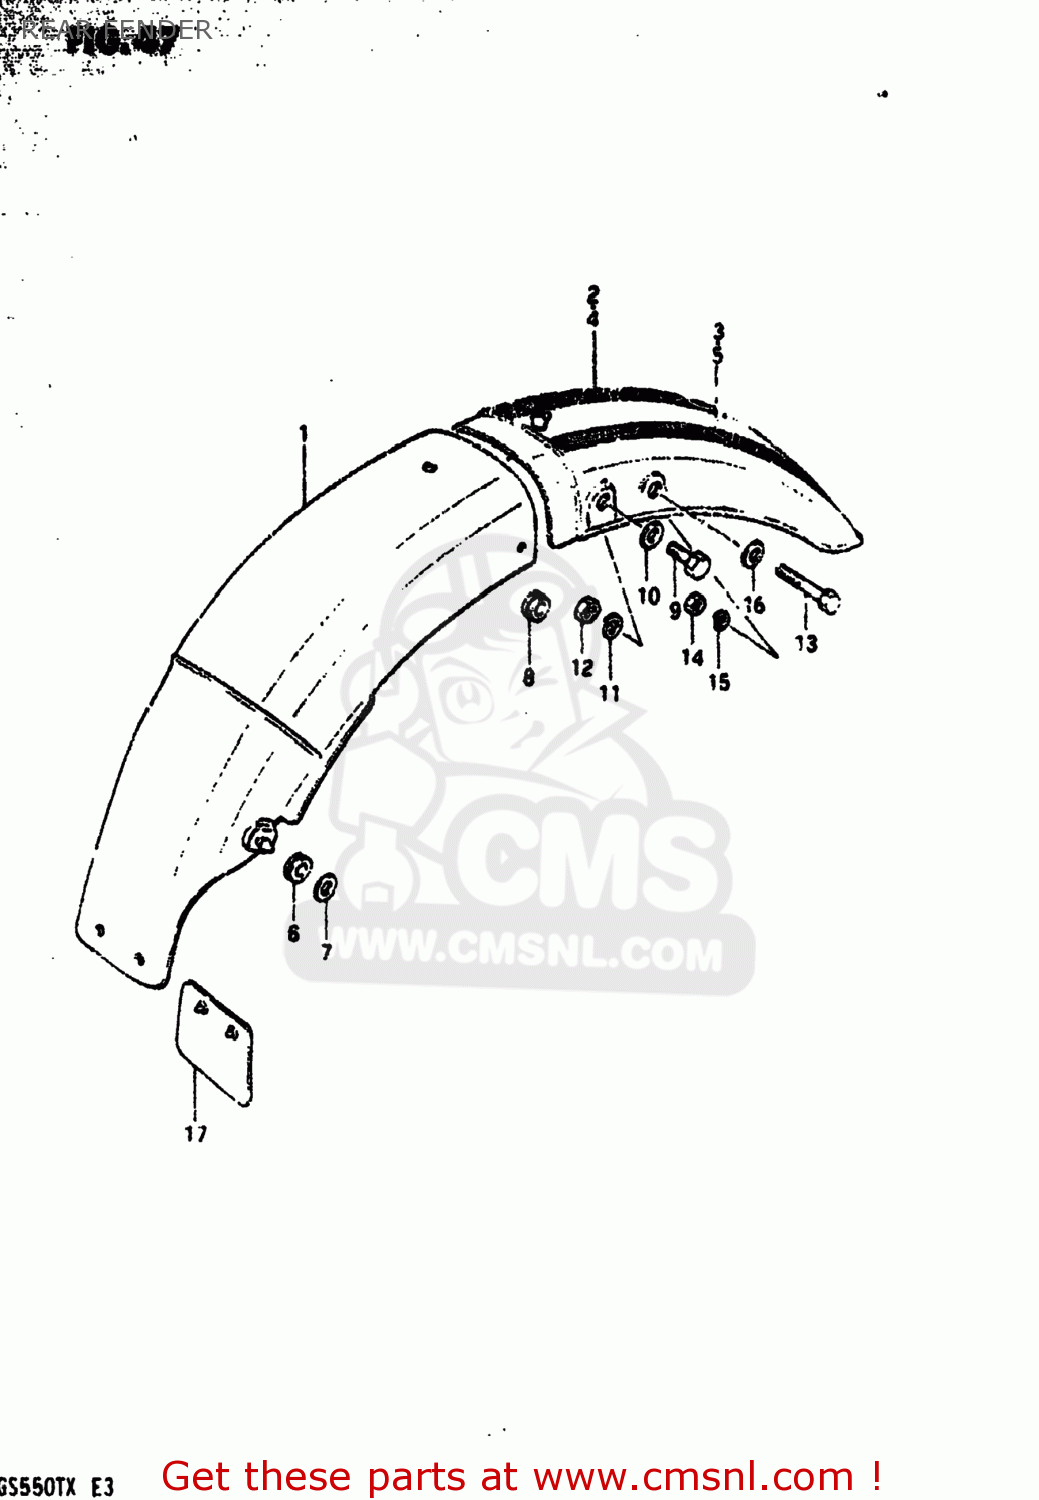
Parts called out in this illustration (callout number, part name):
1	FENDER,REAR
2	FENDER,REAR
3	TAPE SET,REAR FENDER
4	FENDER,REAR
5	TAPE SET,REAR FENDER
6	CUSHION
7	WASHER (5.5X16X1.2)
8	CUSHION
9	BOLT
10	WASHER
11	LOCK WASHER
12	NUT
14	NUT 8MM
15	LOCK WASHER
16	WASHER
17	GUIDE,RR FENDER MUD
